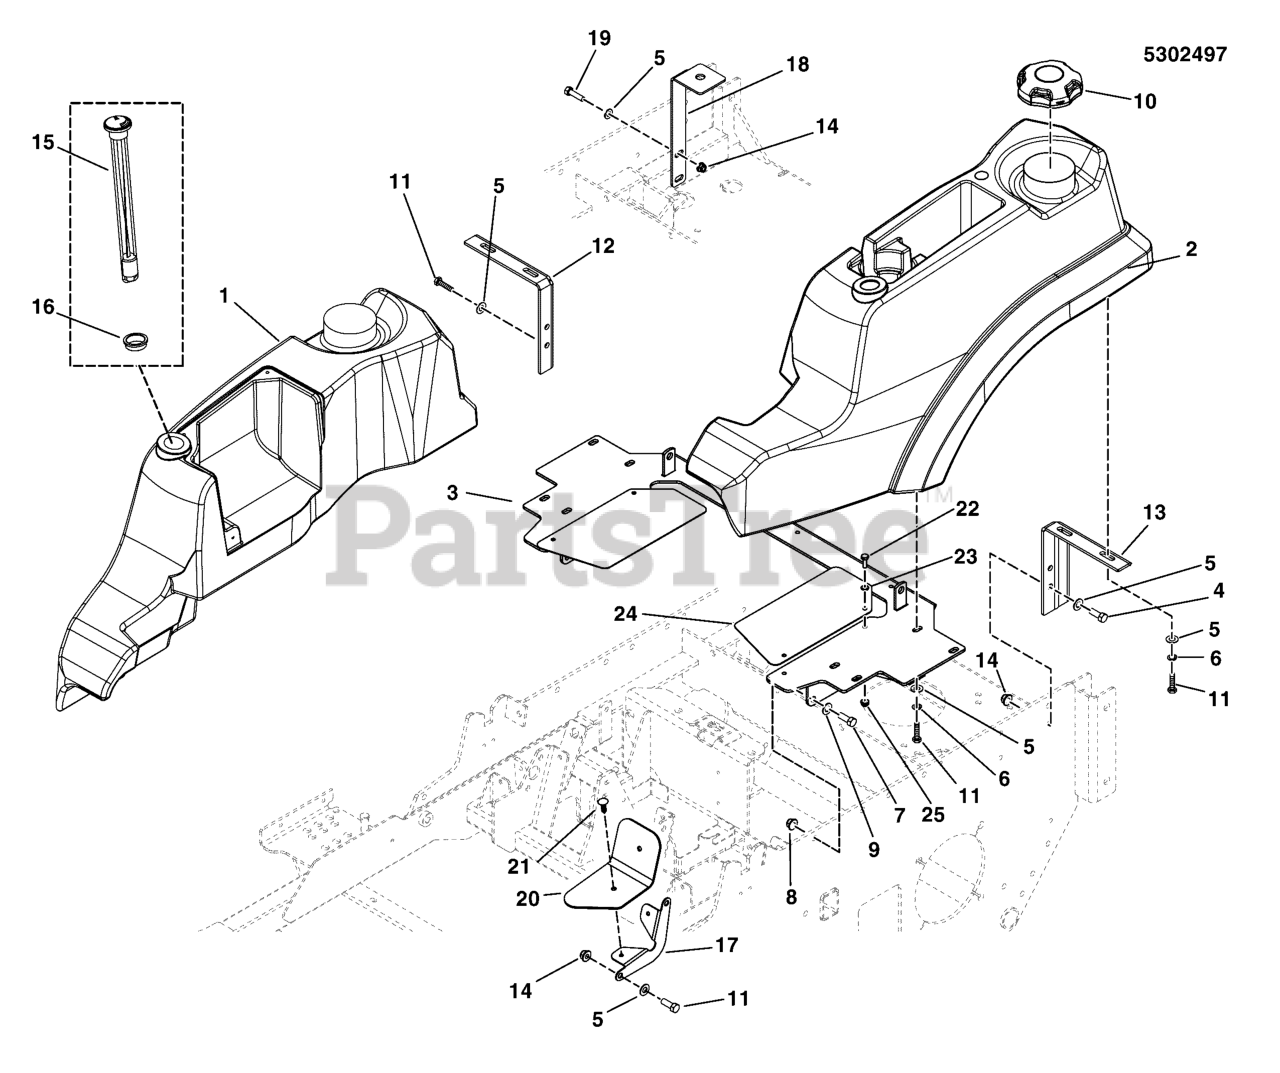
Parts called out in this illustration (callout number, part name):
1	TANK, FUEL, SNAPPER PRO - RH
2	TANK, FUEL, SNAPPER PRO - LH
3	WELD, TANK MOUNT - RED
4	BOLT, 5/16-18 X 1 GD5 YZ
5	WASHER, 5/16" SAE
6	WASHER, 5/16 LOCK CZ
7	BOLT, 3/8-16 X 1" GD5 CZ
8	NUT, 3/8-16 HEX NYLOCK FLANGE
9	WASHER, 3/8 SAE
10	CAP, GASOLINE
11	BOLT, 5/16-18 X 3/4 GD5
14	NUT, 5/16-18 HEX NYLOCK FLANGE
15	GAUGE, FUEL, 12
16	GROMMET, FUEL GAUGE (SV)
17	MOUNT, GUARD, MOTION CTRL - BLK
18	BRACKET, FUEL VALVE, IS3000 - BLK
19	BOLT, 5/16-18 X 1-1/4 GD5 YZ
20	FLAP, RUBBER, MOTION CONTROL, S150XT
21	PUSH RIVET (TREE TYPE), BLACK
22	BOLT, 1/4-20 X 3/4 GD5 YZ
23	WASHER, 1/4 SAE
24	PLATE, GUARD, SEAT - RED
25	NUT, 1/4-20 HEX NYLOCK FLANGE
